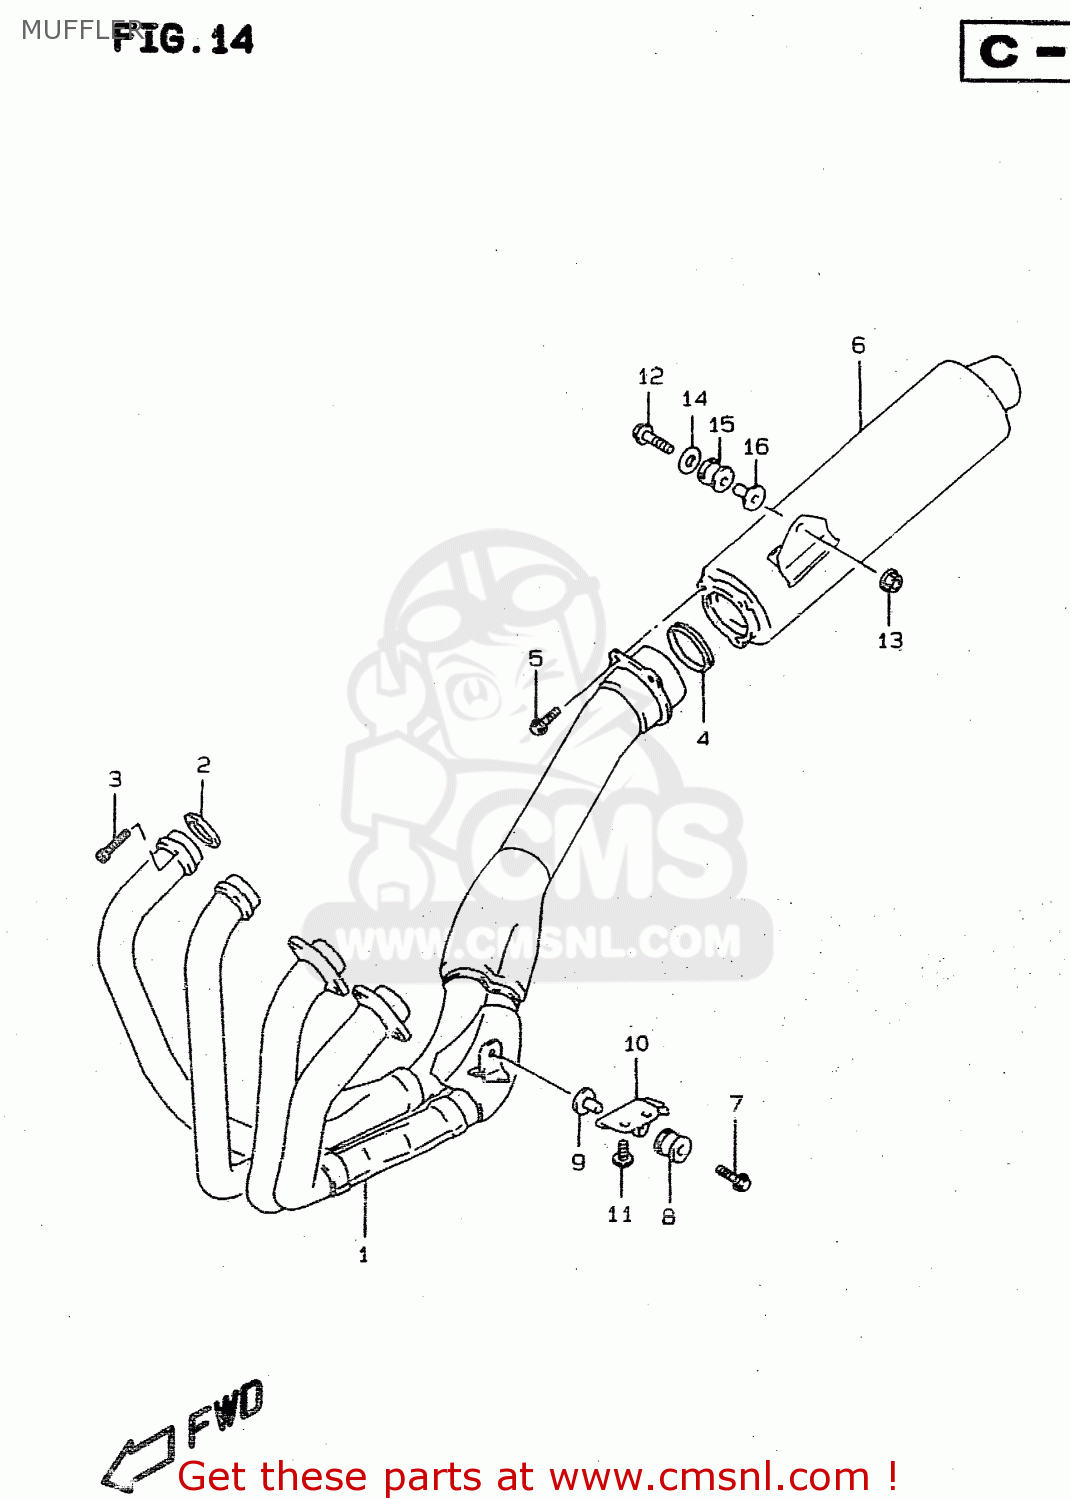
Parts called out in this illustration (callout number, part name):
1	PIPE,EXHAUST
2	GASKET,EXHAUST PIPE
3	BOLT
4	GASKET,MUFFLER JOINT
5	BOLT(8X20)
6	BODY,MUFFLER
7	BOLT 8X45
8	CUSHION
9	SPACER(8.6X12X24.2)
10	BRACKET,MUFFLER SUPPORT FR
11	BOLT
12	BOLT
13	NUT
14	WASHER (8.1X33X1.6)
15	CUSHION
16	SPACER(8.6X12X27.1)
